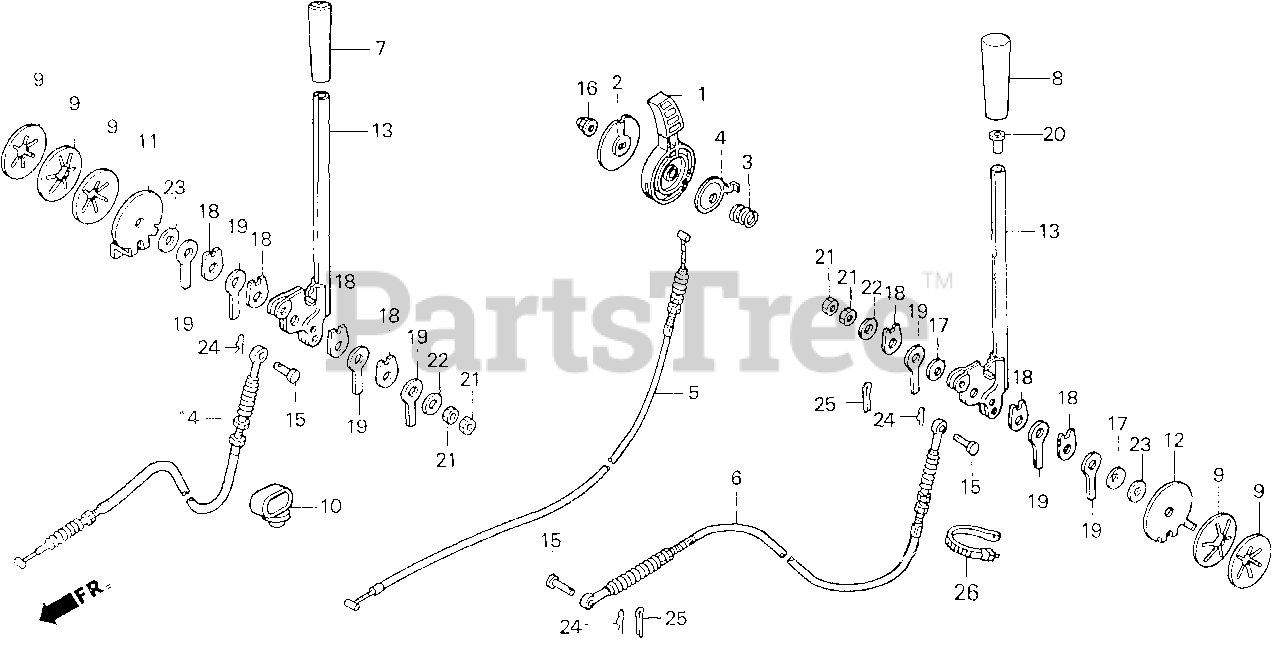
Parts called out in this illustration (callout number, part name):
1	LEVER, THROTTLE
2	PLATE, THROTTLE LEVER
3	SPRING, THROTTLE LEVER
4	SEAT, SPRING
5	CABLE, THROTTLE
6	CABLE, CHANGE
7	GRIP, CHANGE LEVER
8	GRIP, CHANGE LEVER
9	SPRING, ADJUSTING ARM
10	CLAMP, CABLE
11	PLATE, R. STOPPER
12	PLATE, L. STOPPER
13	LEVER, CHANGE
14	CABLE, CHUTE GUIDE
15	PIN, CONTROL BOX SETTING
16	NUT, CAP (6MM)
17	WASHER, LOCK
18	WASHER, FRICTION
19	WASHER, FRICTION SETTING
20	COLLAR, CHANGE LEVER
21	NUT, HEX. (8MM)
22	WASHER, PLAIN (8MM)
23	WASHER, PLAIN (8MM)
24	PIN, SPLIT (2.0X12)
25	PIN, LOCK (6MM)
26	BAND, SUCTION HOSE (BLACK)
